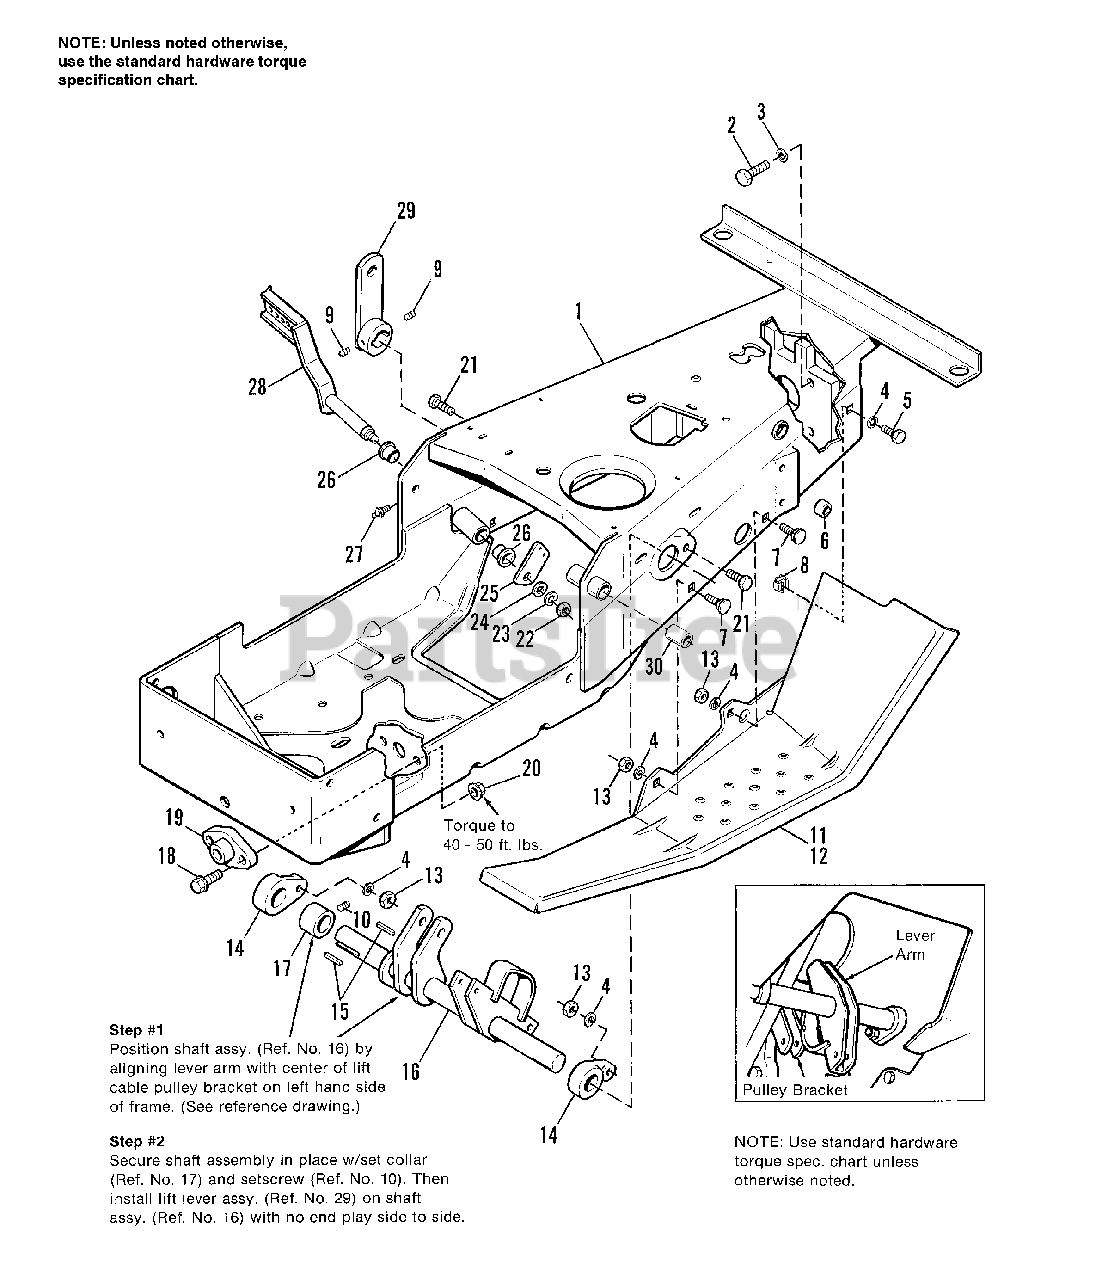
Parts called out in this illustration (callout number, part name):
1	FRAME ASSEMBLY, w/Bushings
2	CAPSCREW, Hex Hd, 7/16-14 x 1-1/2"
3	LOCKWASHER, 7/16
4	LOCKWASHER, 5/16
5	CAPSCREW, Hex Hd, 5/16-18 x 3/4
7	CARRIAGE BOLT, 5/16-18 x 3/4
8	NUT, Speed, 5/16-18
9	SETSCREW, 5/16-18 x 1/4
10	SETSCREW, 5/16-18 x 1/2
11	FOOTREST, L.H.
12	FOOTREST, R.H.
13	NUT, Hex, Full, 5/16-18
14	BEARING, Lift Lever
16	SHAFT ASSEMBLY, Lift (Hydro Lift)
17	COLLAR, Set
18	CAPSCREW, Hex Flange Hd, Whiz Lock, 3/8-16 x 1-1/4
19	BEARING, Pivot
20	LOCKNUT, Hex, Flange, 3/8-16
21	CAPSCREW, Hex Hd, 5/16-18 x 1-1/4
22	NUT, Hex, Full, 3/8-16
23	LOCKWASHER, 3/8
24	WASHER, Plain, 3/8
25	ARM, Foot Pedal
27	FITTING, Grease
28	PEDAL ASSEMBLY, Foot
29	LEVER ASSEMBLY, Front Lift
30	BEARING, Interim Pinion
